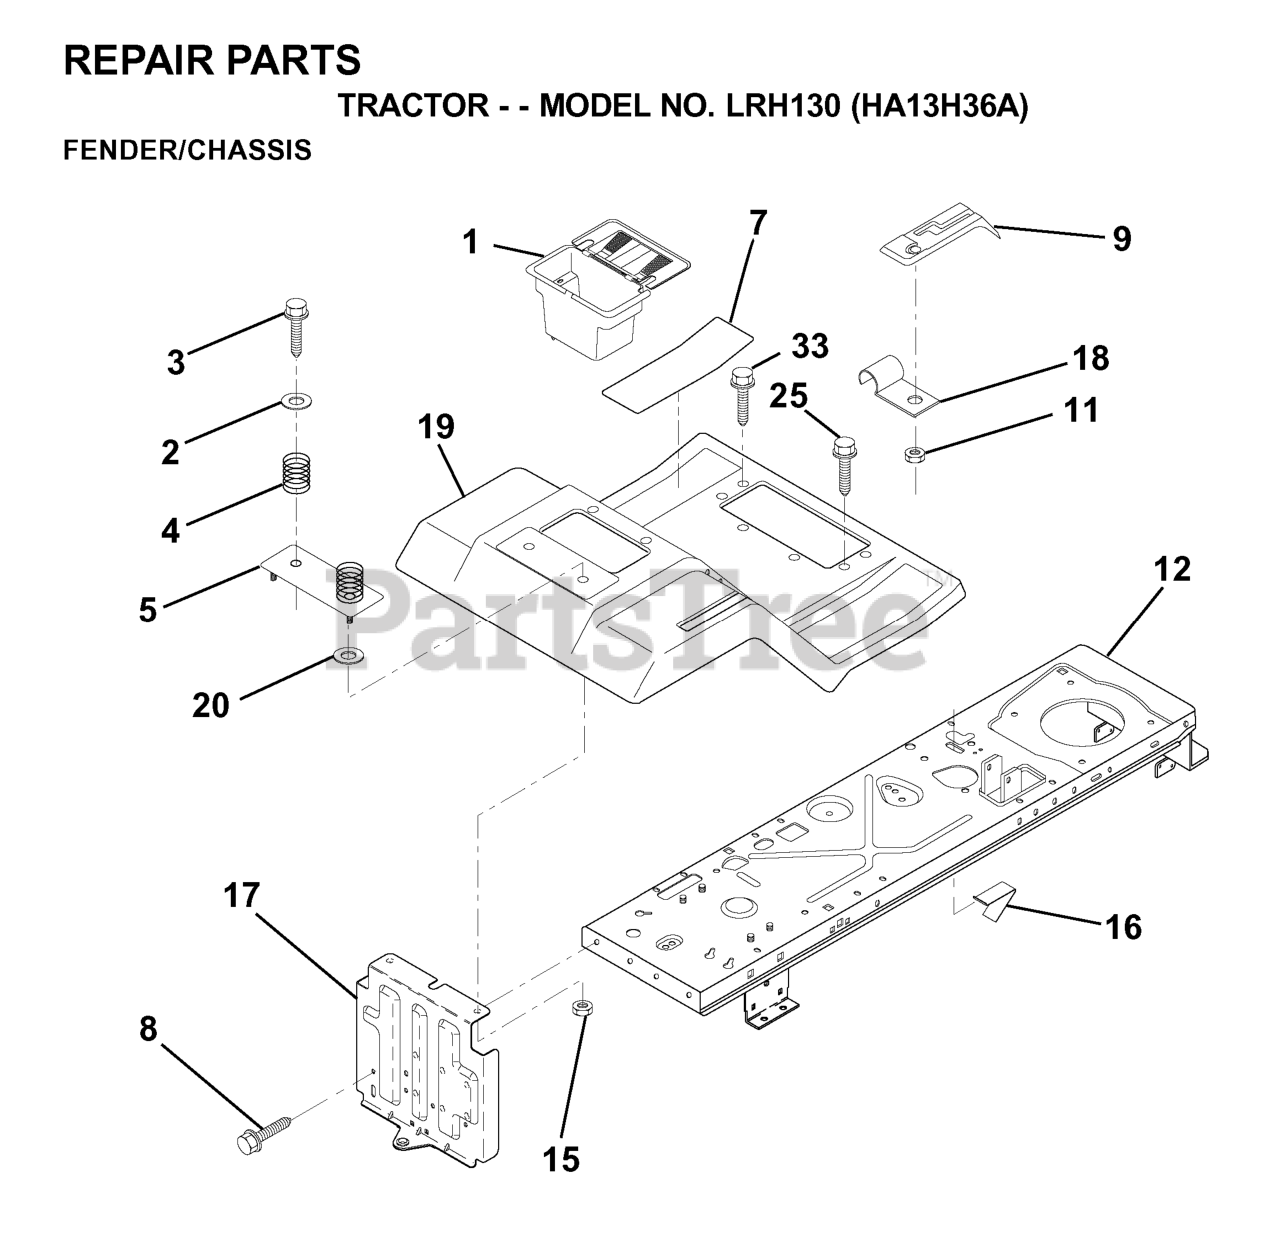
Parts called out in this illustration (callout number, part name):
1	CASE BATTERY MECH HINGE
2	WASHER
3	SCREW
4	SPRING COMPRESSION
5	PLATE ASM BATTERY
7	FOOTREST PAD
8	SCREW 5/16"
11	NUT.PUSH.3/16
15	Nut, Keps Blk Hex 1/4-20 UNC
16	SWITCH ACTUATOR
18	CLIP,INSULATOR
19	FENDER/FOOTREST
20	WASHER
25	Screw Tapping 5/16-18 Unc
33	Screw Hex Wsh Thdroll 5/16-18 x 1
